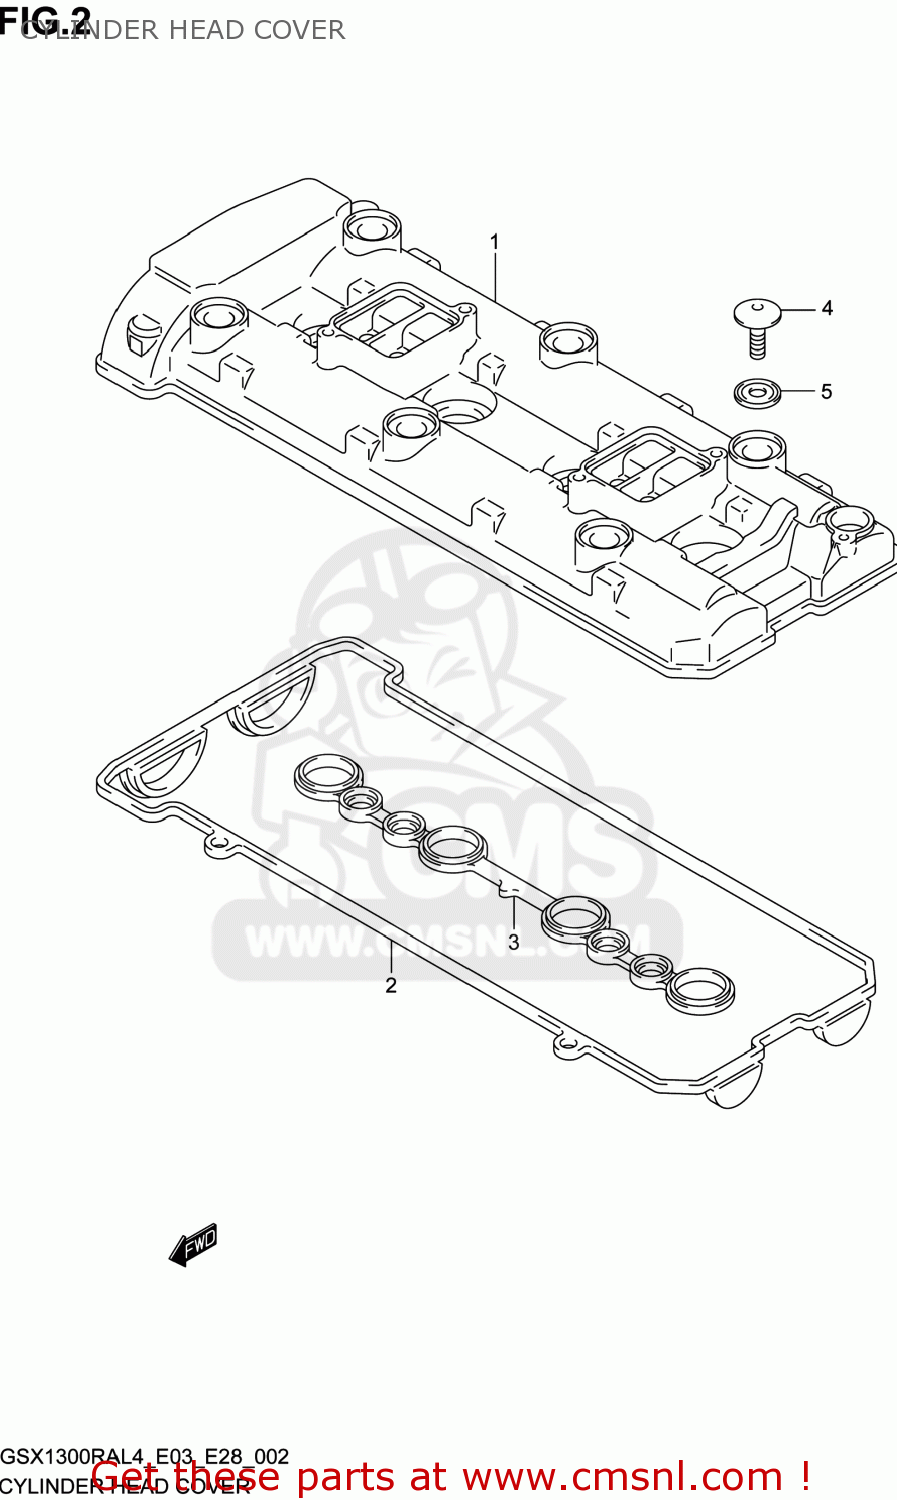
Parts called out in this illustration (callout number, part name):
1	COVER,CYLINDER HEAD
2	GASKET,CYL HEAD COVER NO.1 (NAS)
3	GASKET,CYL HEAD COVER NO.2 (NAS)
4	BOLT(7X17.5)
5	WASHER,CYL HEAD COVER
